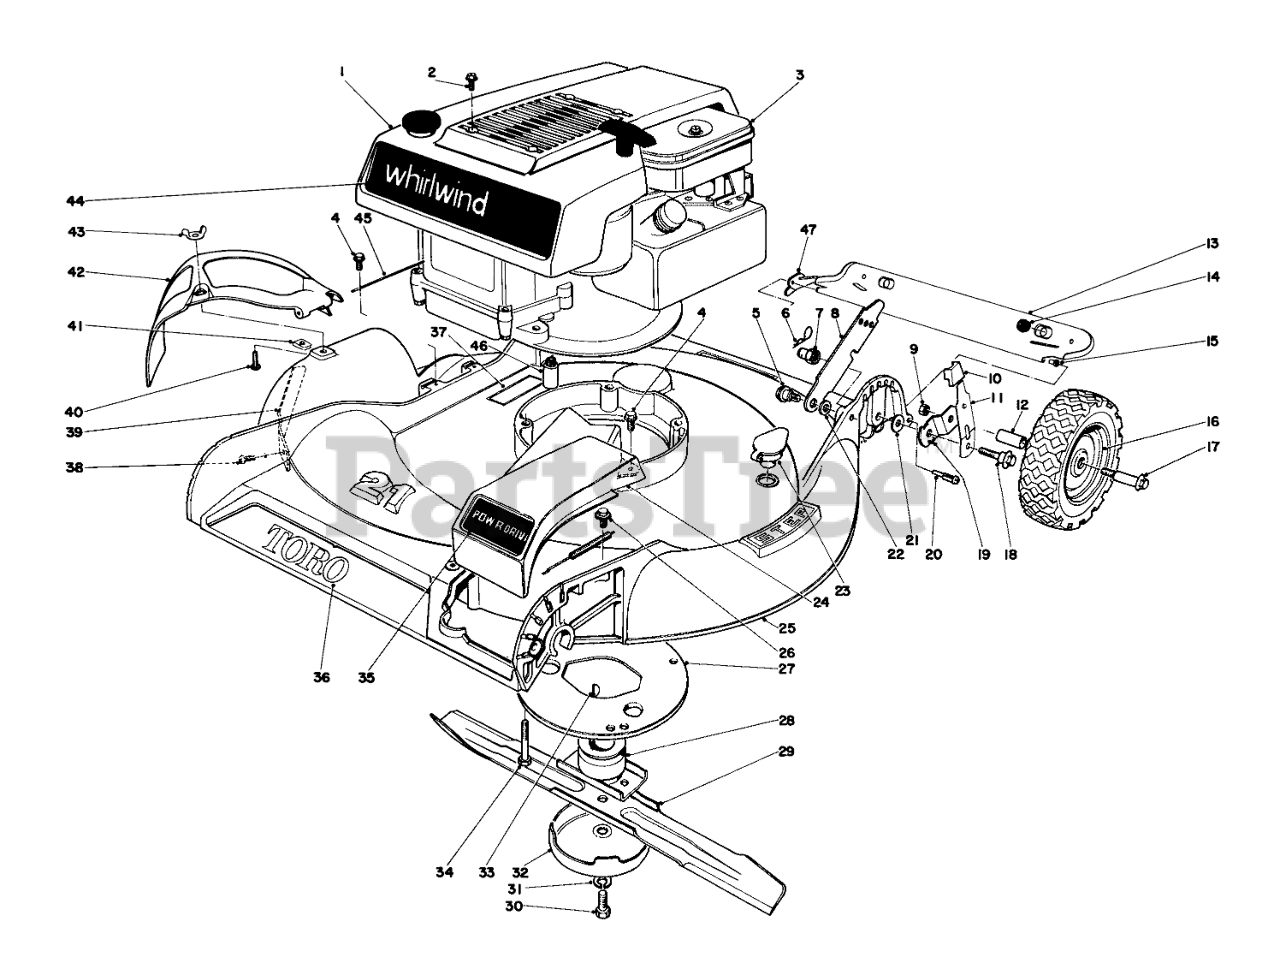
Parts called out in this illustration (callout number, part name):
1	Shroud
2	8X1/2 SELF TAP SCREW
3	Engine
4	SCREW
5	SCREW-SHOULDER
6	PIN-COTTER, HAIR
7	HANDLE PIVOT NUT
8	Latch
9	Nut
10	Arm Knob
11	Spring Arm
12	Bushing
13	Rear Safety Shield (Incl. Ref. #14 & 15)
14	SKID BUTTON
15	SAFTEY SHIELD BUSHING
16	Rear Wheel w/Tire (Incl. Ref. #12)
18	PIVOT SCREW
19	Pivot Arm
20	SAFTEY SHIELD SCREW
21	WASHER-PIVOT
22	SPACER
23	WASHOUT PLUG
24	Guard, Belt
25	Housing
26	Screw
27	Grass Guard
28	BLADE RETAINER WA
29	Blade
30	SPECIAL SCREW
31	WASHER-LOCK
32	AntiScalp Cup
33	KEY-WOODRUFF
34	3/8-16 X 2-3/4 CAPSCR
35	Decal Power Drive
36	Decal Toro
37	Decal
39	Bar Safety
41	NUT-SPEED
42	Deflector
43	NUT-WING SPECL
44	Decal Whirlwind
45	HINGE PIN
46	OIL DRAIN EXTENSION
47	Restraint R.H.
